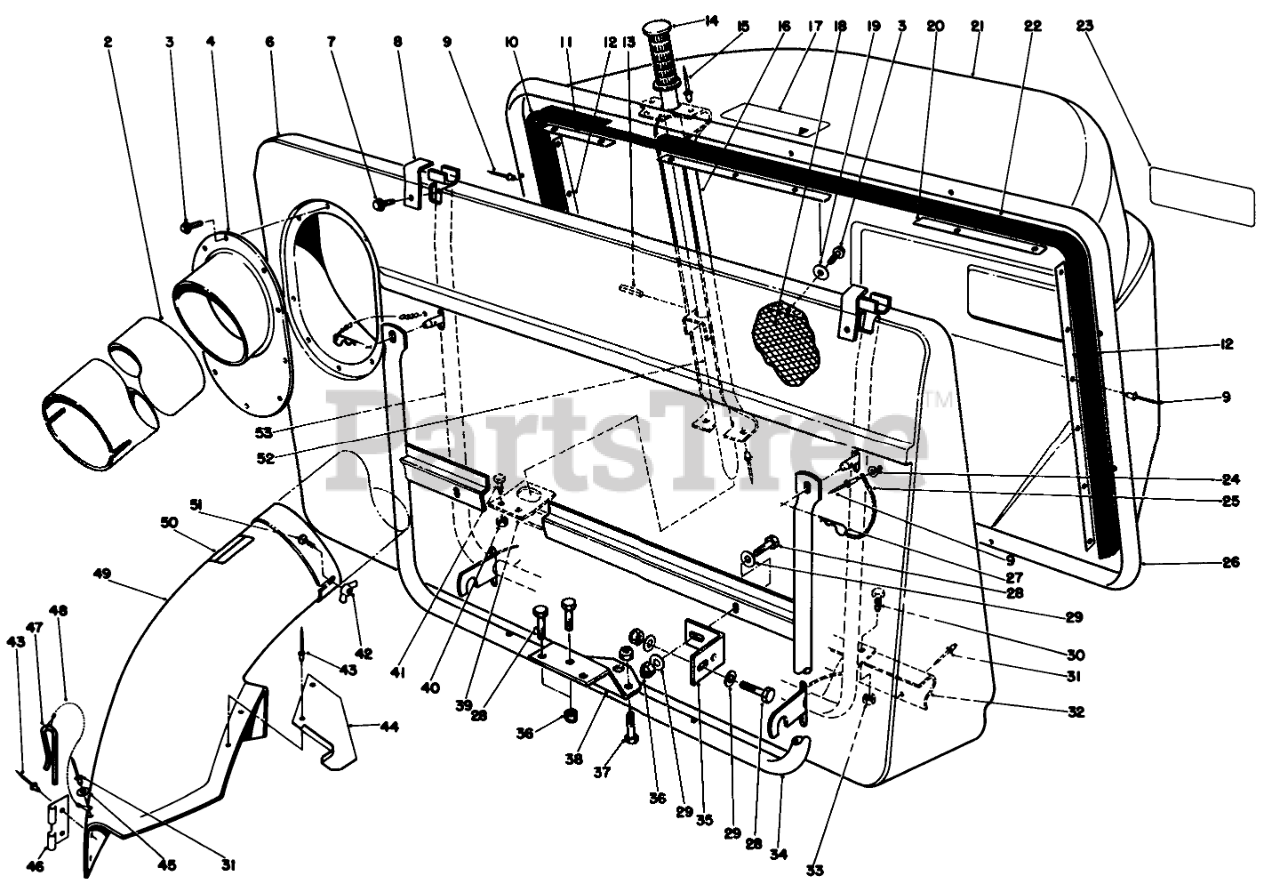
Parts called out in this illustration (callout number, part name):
2	TUBE(ROUND&LONG)
3	SCREW-HWHTF
4	DUCT ADAPTER
6	Bag Front
7	SCREW-HWH
8	RETNR PIVOT BRKT
10	RH BAG SEAL
11	RETNR TOP EXT.
12	BAG RETNR EXT.
13	PIN-ROLL
14	Grip Handle
15	RIVET-POP
16	DUMP HDLE CHANL WA
17	Decal Warning
18	Screen Bag
19	WASHER-FLAT
20	Retainer
21	REAR GRASS BASKET
22	Seal-Bag LH.
23	EASY EMPTY BAG DECAL
24	WASHER
25	10 LINK CHAIN W/O HOOK
26	BAG SUPT ASM FRM
27	PIN-HAIR
28	SCREW-HH
29	WASHER-PLAIN
30	SCREW-HH
31	RIVET-BLIND
32	FRAME SUPT BRKT B
33	NUT-LOCK, CONE
34	BAG SUPPORT WA
35	MTG BRACKET
36	NUT-LOCK, NI
37	SCREW-HH
38	MTG PLATE B
39	Hanger-Frame Lower
40	NUT-LOCK, CONE
41	SCREW-HH
42	NUT-WING SPECL
43	RIVET-BLIND
44	CHUTE SUPT BRKT
45	WASHER-PLAIN
46	BRACKET-MOUNTING, CHUTE
47	PIN-LOCKING, CHUTE
48	LANYARD
49	Chute Assembly (Incl. Ref. #31, 41-50)
50	DECAL-DANGER
51	BOLT-CARR
52	DUMP HANDLE ASM
53	Bag Frame
